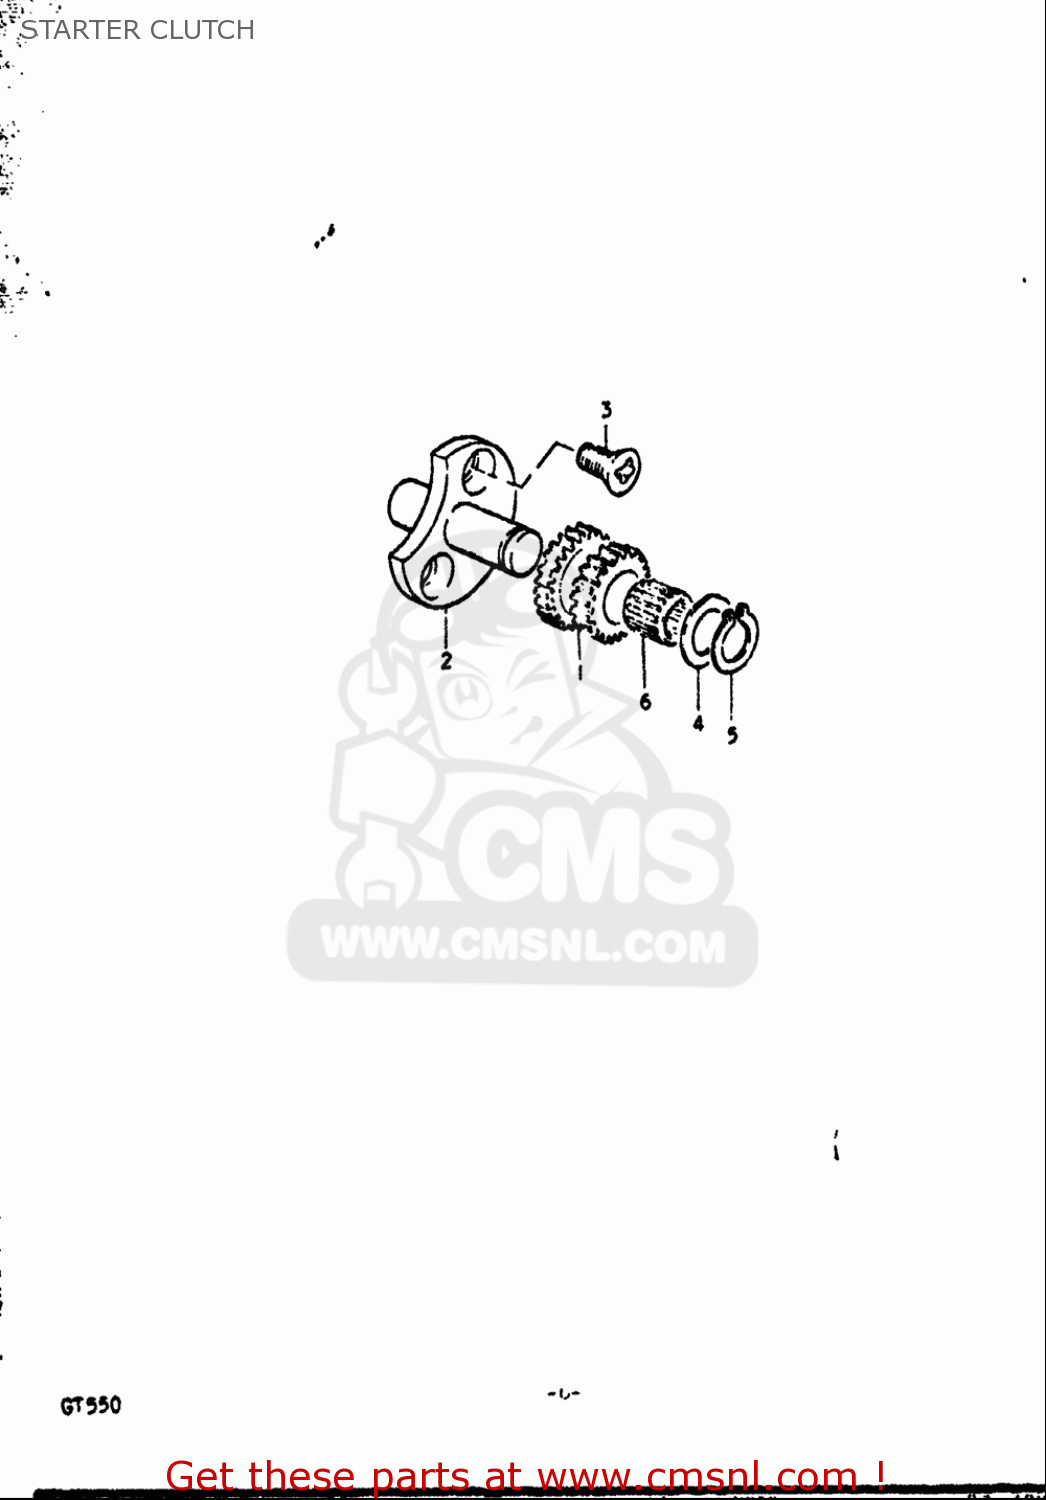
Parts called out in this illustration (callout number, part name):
3	SCREW
4	WASHER,THRUST
5	CIRCLIP,12 MM
